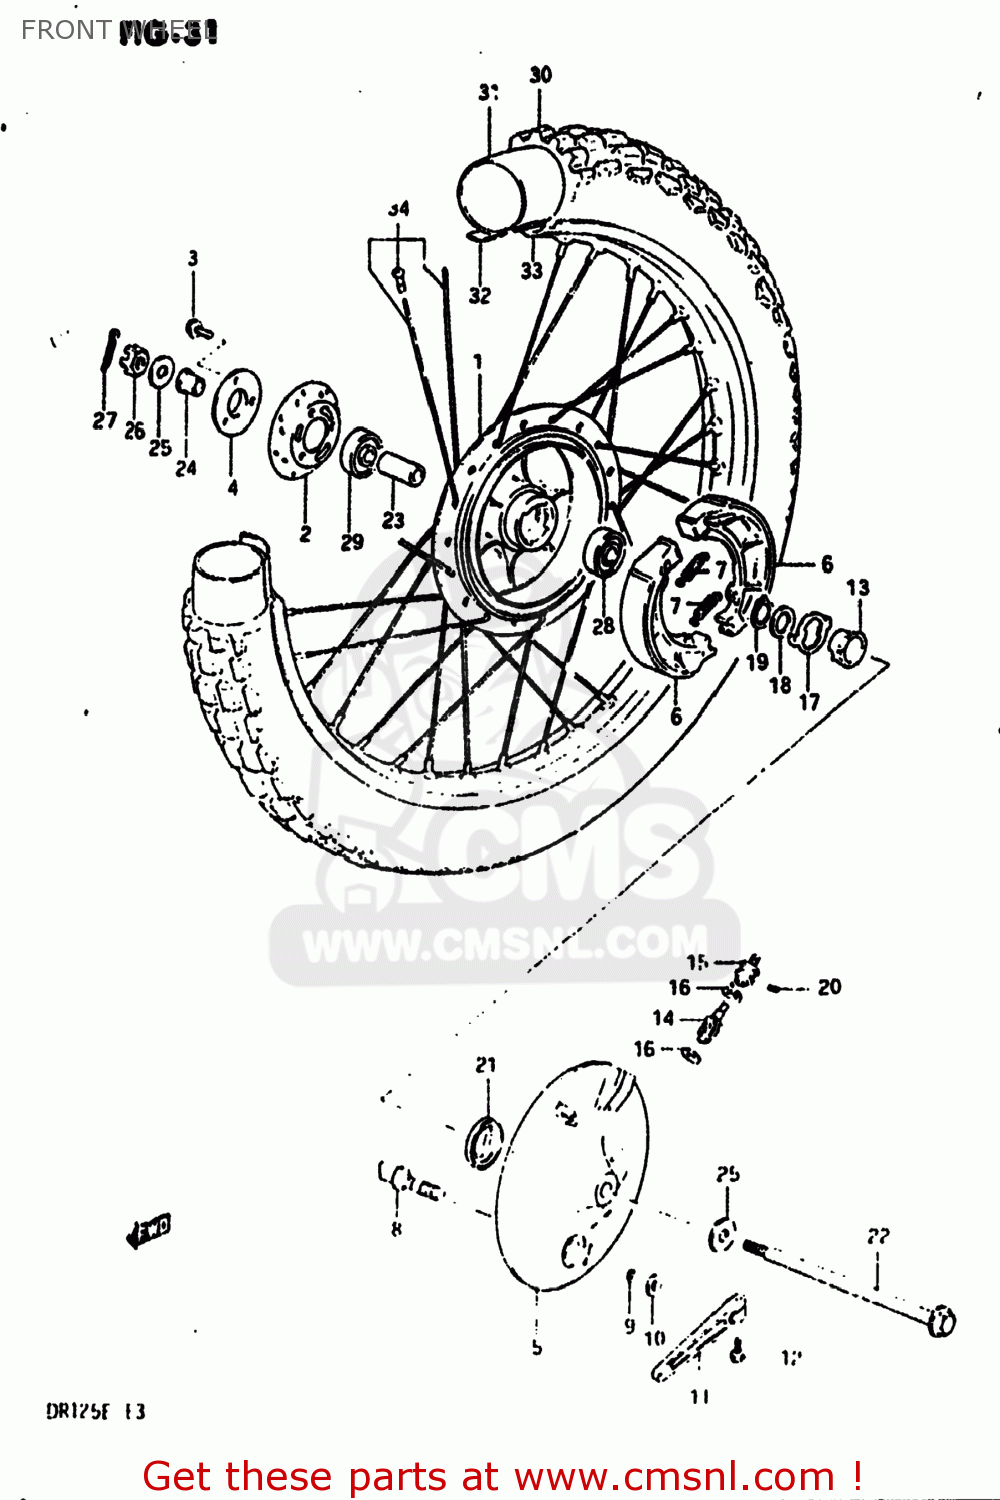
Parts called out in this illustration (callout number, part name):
1	HUB,FR WHEEL
2	FLANGE,FR HUB,R
3	BOLT
4	PLATE,FRONT HUB BEARING
5	PANEL,FRONT HUB
6	SHOE,BRAKE
7	SPRING(L:34)
8	CAM,FRONT BRAKE
9	O-RING (D:2.4 ID:13.8)
10	WASHER (14.5X22X1.6)
11	LEVER,FRONT BRAKE CAM
12	BOLT
13	GEAR,SPEEDOMETER
14	PINION,SPEEDOMETER
15	BUSH,METER GEAR OUTER
16	WASHER (5.1X9X0.4)
17	DRIVER,SPEEDOMETER GEAR
18	WASHER(18.5X24X1)
19	CIRCLIP
20	SCREW
21	OIL SEAL (43X58X7)
22	AXLE,FRONT
23	SPACER (12.6X19X52)
24	SPACER,FR AXLE,R
25	WASHER
26	NUT 12MM
27	COTTER PIN
28	BEARING
29	BEARING, RH
30	TIRE,FRONT
31	TUBE
32	PROTECTOR,WHEEL,INNER
33	RIM,FRONT WHEEL
34	SPOKE SET,FRONT
